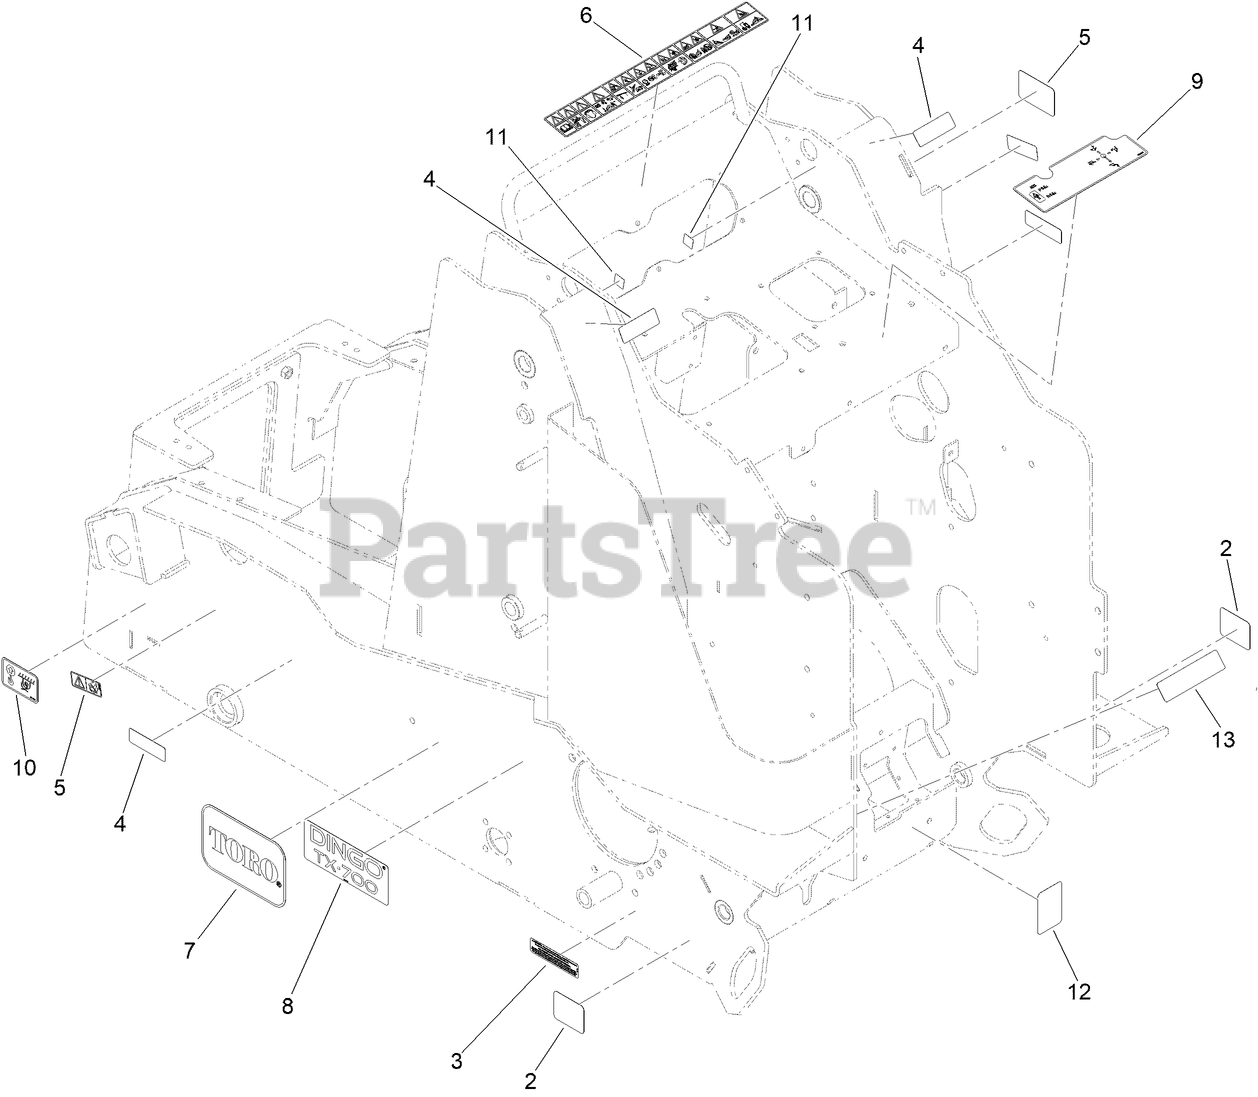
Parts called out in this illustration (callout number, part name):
2	DECAL-TIE DOWN
3	DECAL-ARRESTOR, SPARK
4	DECAL-WARNING, PINCH POINT
5	DECAL-SURFACE, HOT
6	DECAL-SAFETY
7	DECAL-TORO LOGO
8	DECAL-DINGO TX700
9	DECAL-LOADER CONTROL
10	DECAL-LIFT/TIE DOWN
11	DECAL-POINT, LIFT
12	REFLECTOR
13	DECAL-PARKING BRAKE
